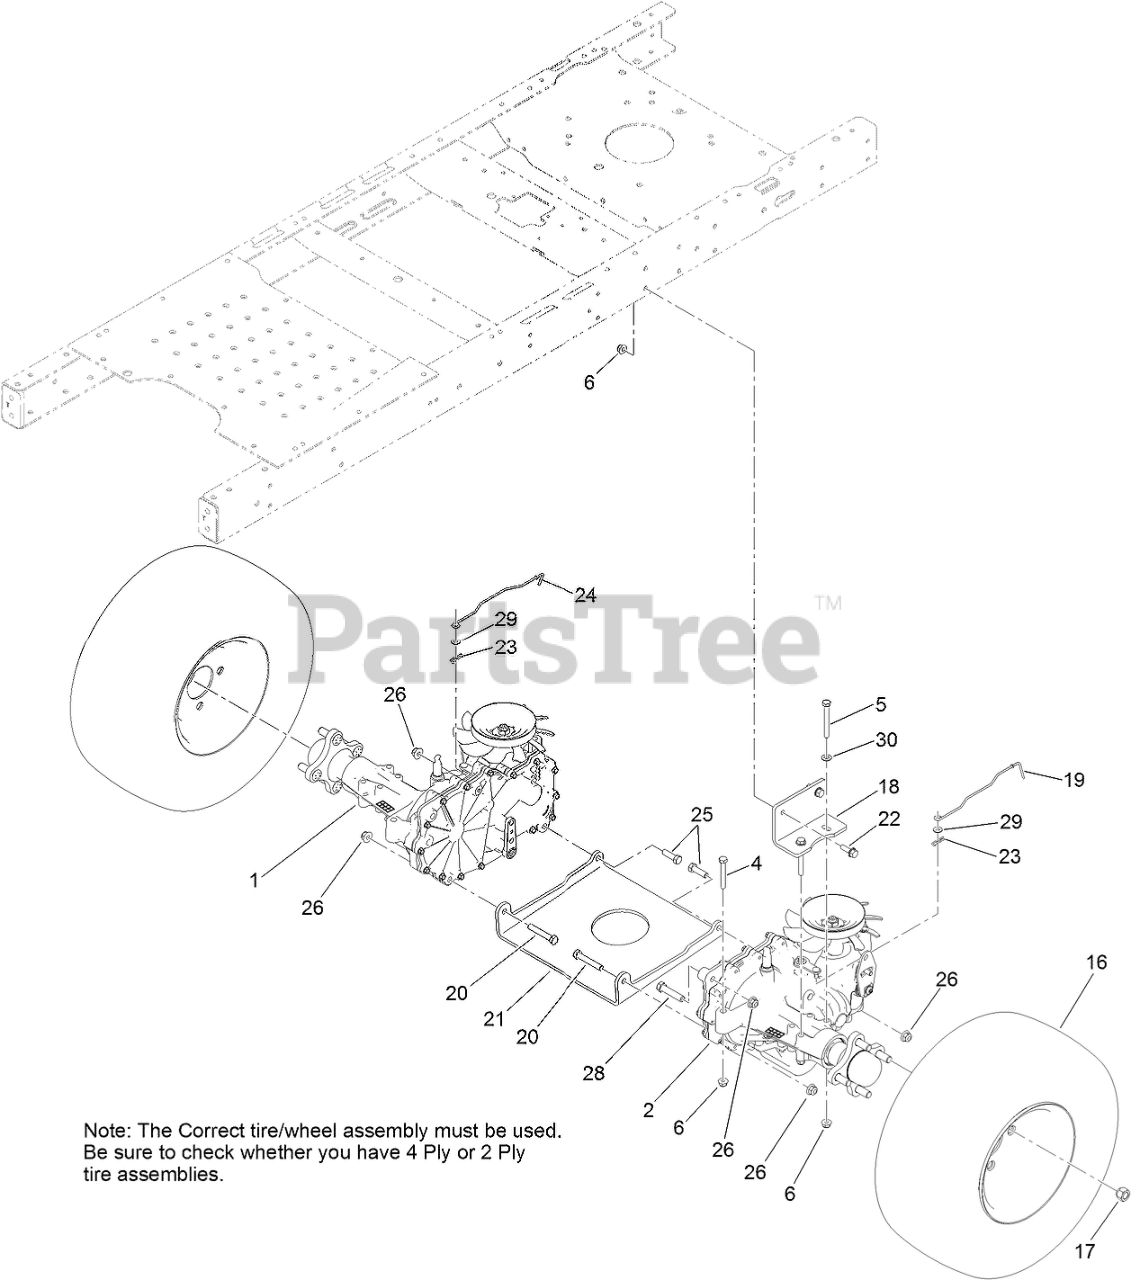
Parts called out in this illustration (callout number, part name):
1	RH HYDRO TRANSMISSION ASM
2	LH HYDRO TRANSMISSION ASM
4	SCREW-HH
5	SCREW-HH
6	NUT-HF, NI
16	4 PLY WHEEL AND TIRE ASM
16	2 PLY TIRE AND WHEEL ASM
17	NUT-LUG
18	MOUNT-HYDRO
19	ROD-BYPASS, LH
20	SCREW-HH
21	PLATE-CROSS, HYDRO
22	SCREW-HHF
23	PIN-COTTER
24	ROD-BYPASS, RH
25	SCREW-HH
26	NUT-HF, NI
28	SCREW-HH
29	WASHER
30	WASHER-PLAIN
